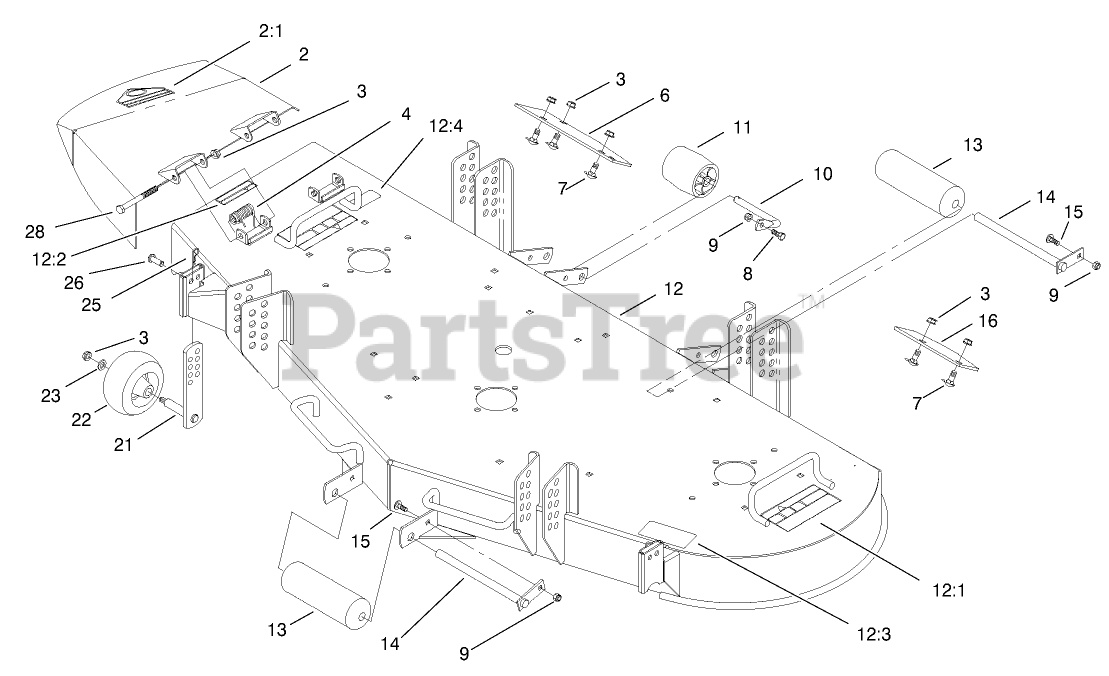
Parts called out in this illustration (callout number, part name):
2	CHUTE ASM
2:1	DECAL-DANGER
3	NUT-LOCK, NI
4	SPRING
6	PLATE-WEAR, RH
7	BOLT-CARR
8	SCREW-HH
9	NUT-LOCK, NI
10	ROLLER-SHAFT
11	Roller
12	DECK ASM
12:1	DECAL-DANGER, THROWN OBJECT
12:2	DECAL-DANGER
12:3	DECAL - WHEEL ADJUSTMENT
12:4	DECAL-STD, SAFETY
13	ROLLER-ANTI SCALP
14	ROLLER-SHAFT
15	BOLT-CARR
16	PLATE-WEAR, LH
21	GAGE-WHEEL
22	WHEEL-GAGE
23	WASHER-FLAT
25	PIN-HAIR
26	PIN-CLEVIS
28	SCREW-HH
